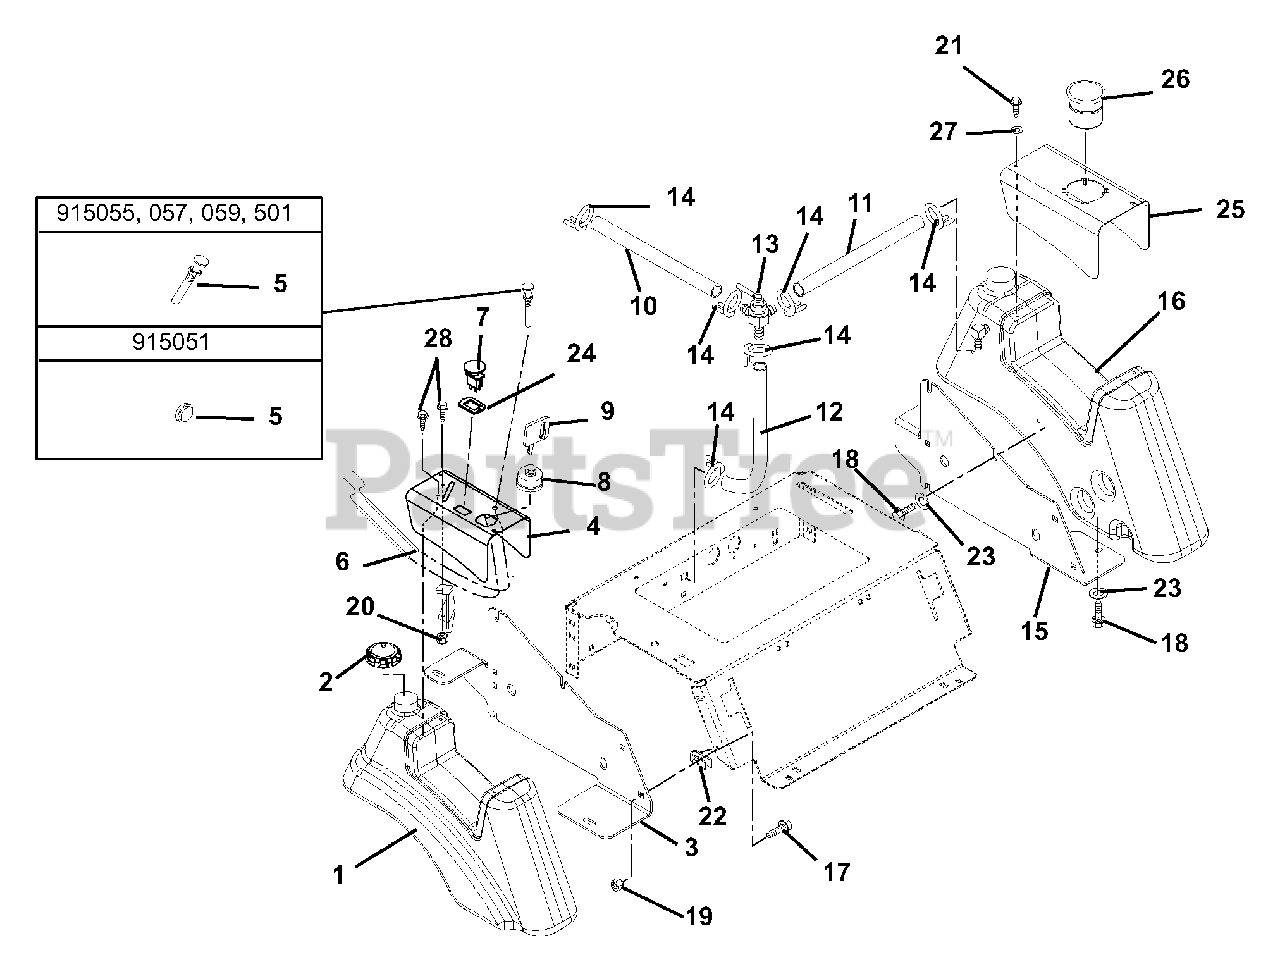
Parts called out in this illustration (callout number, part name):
1	FUEL TANK, RH
2	FUEL CAP
3	SEAT PLATE, RH
4	RH CONSOLE
5	CHOKE CABLE
6	THROTTLE CABLE
7	SWITCH, CLUTCH
8	KEY SWITCH
9	KEY -W/CAP
10	GAS LINE-BULK 1/4" I.D.
11	GAS LINE-BULK 1/4" I.D.
12	GAS LINE-BULK 1/4" I.D.
13	VALVE, FUEL
14	CLAMP-HOSE WIRE .490/.510X.116
15	SEAT PLATE, LH
16	FUEL TANK, LH
17	@BLT-RDHDSQNK .38-16X1.00 G5YZ
18	BLT-SERHFWH .312-18X.75 YWZC
19	@NUT-LK-NYL-FLG .38-16 YWZC
20	@NUT-LK-NYL 10-24 W/INSRT YWZC
21	SCR-MCH 10-24X3/8 SL HEX YWZC
22	RETAINER, .38 PUSH-ON
23	WSHR-FL-STL .328X1.0X.094 YWZC
24	SHIM,PTO SW (DELTA #972301)
25	LH CONSOLE
26	CUPHOLDER
27	WASHER, FENDER 3/16X3/4 YWZC
28	@SCR-MCH 10-24X.50 HWH YWZC
